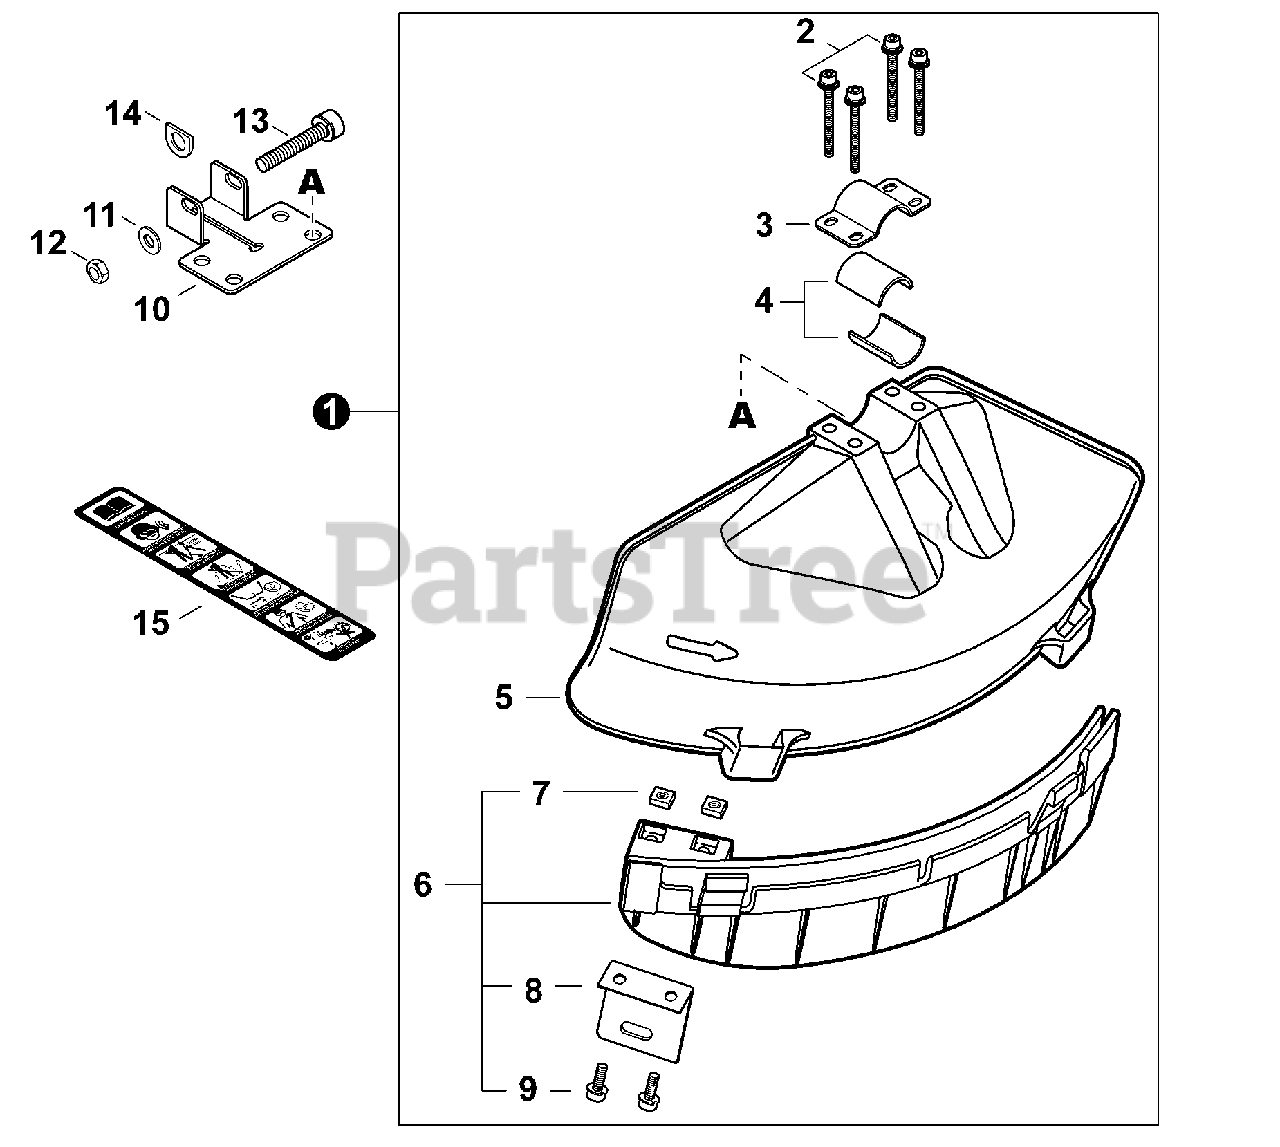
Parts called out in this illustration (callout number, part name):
1	DEBRIS SHIELD KIT
2	BOLT M5x45
3	CLAMP, UPPER
4	SPACER 26
5	SHIELD, DEBRIS PLASTIC
6	DEBRIS SHIELD EXTENSION ASSY
9	BOLT 5x16
10	PLATE, SHIELD MOUNTING
11	WASHER 6.5x13x1
12	NUT, HEX M6
13	BOLT M6x40
14	D-WASHER
15	LABEL - CAUTION (BLADE CAPABLE)
